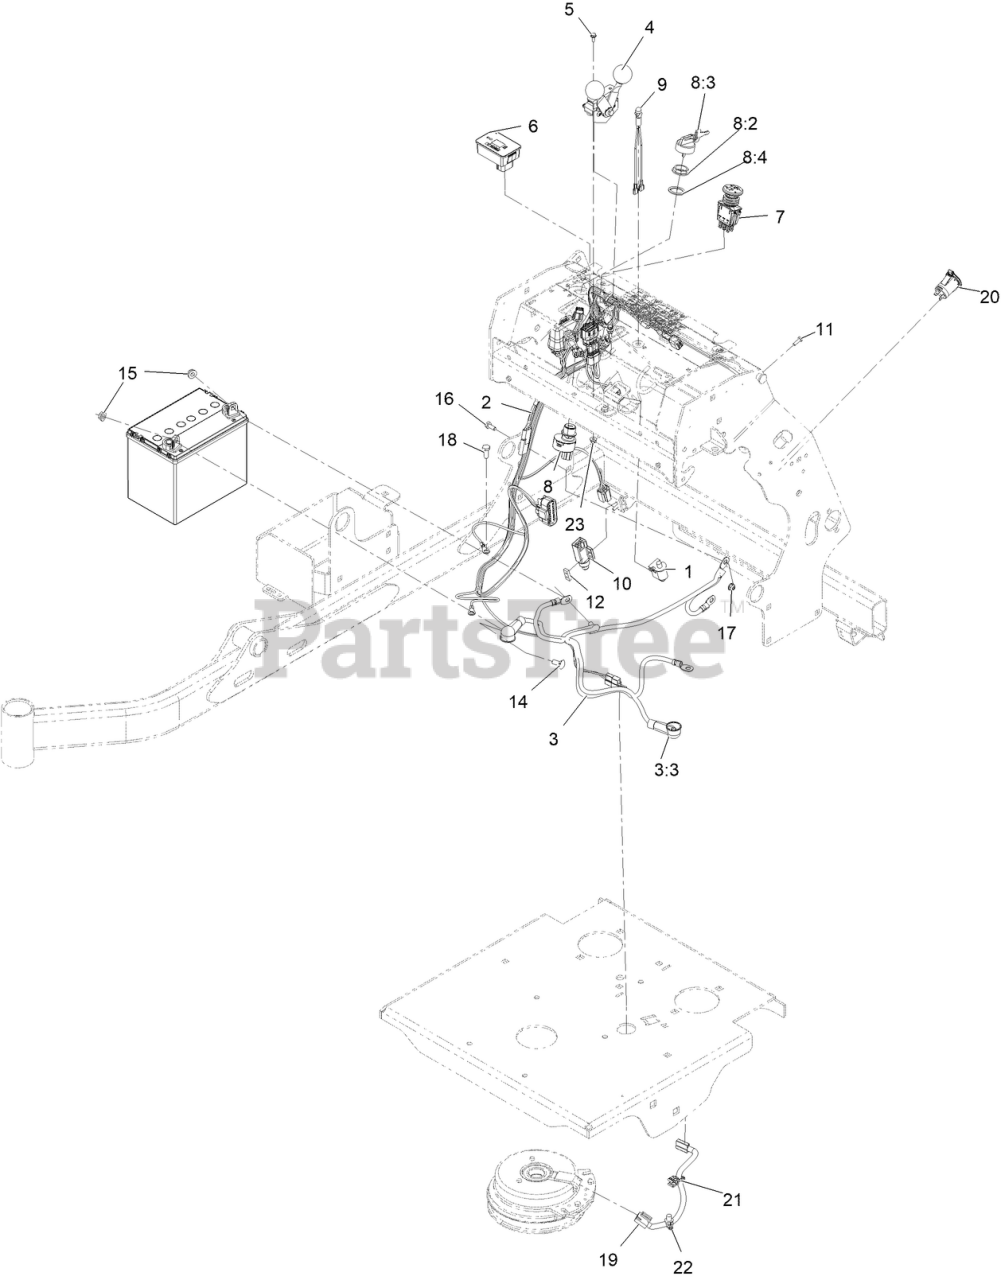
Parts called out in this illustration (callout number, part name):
1	SWITCH-BAIL
2	HARNESS-WIRING
3	HARNESS-BATTERY
3:3	Insulator-Lug, Red
4	THROTTLE CONTROLLER-ETC
5	SCREW-HWH
6	MODULE ASM HOUR METER
7	SWITCH, PTO 10A
8	IGNITION SWITCH ASM
8:2	NUT-MOUNTING
8:3	IGNITION KEY SET
8:4	WASHER-BACKUP
9	INDICATOR-LED, RED
11	SCREW-PPH
12	PLATE-TAPPED
14	BOLT-CARR
16	SCREW-HH
18	SCREW-HH
19	HARNESS-CLUTCH PIGTAIL
20	PORT-POWER, 12V
21	Clip-Edge
22	CLIP-TIE
